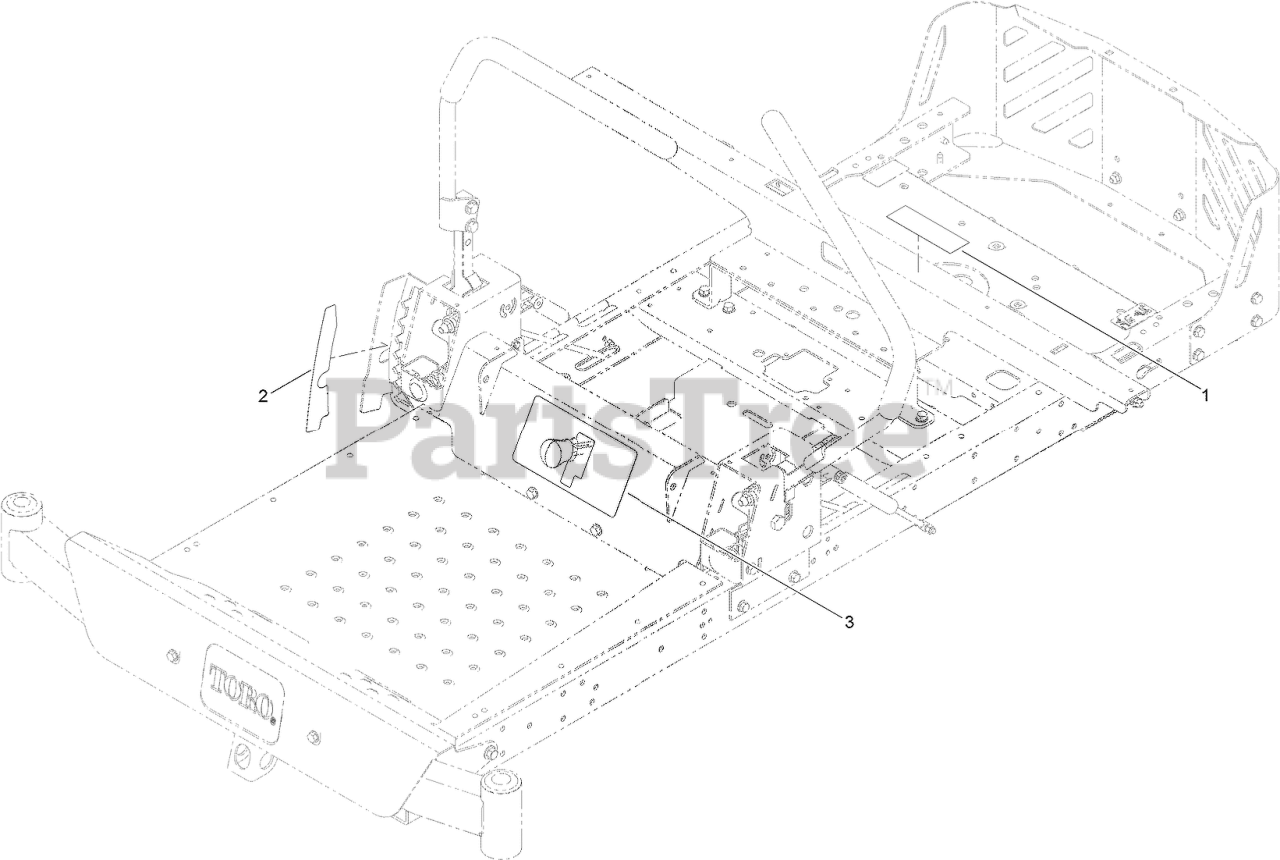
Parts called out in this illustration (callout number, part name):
1	DECAL-SERVICE, CE
2	DECAL-HOC, CE
3	DECAL-CONTROL, SPEED
